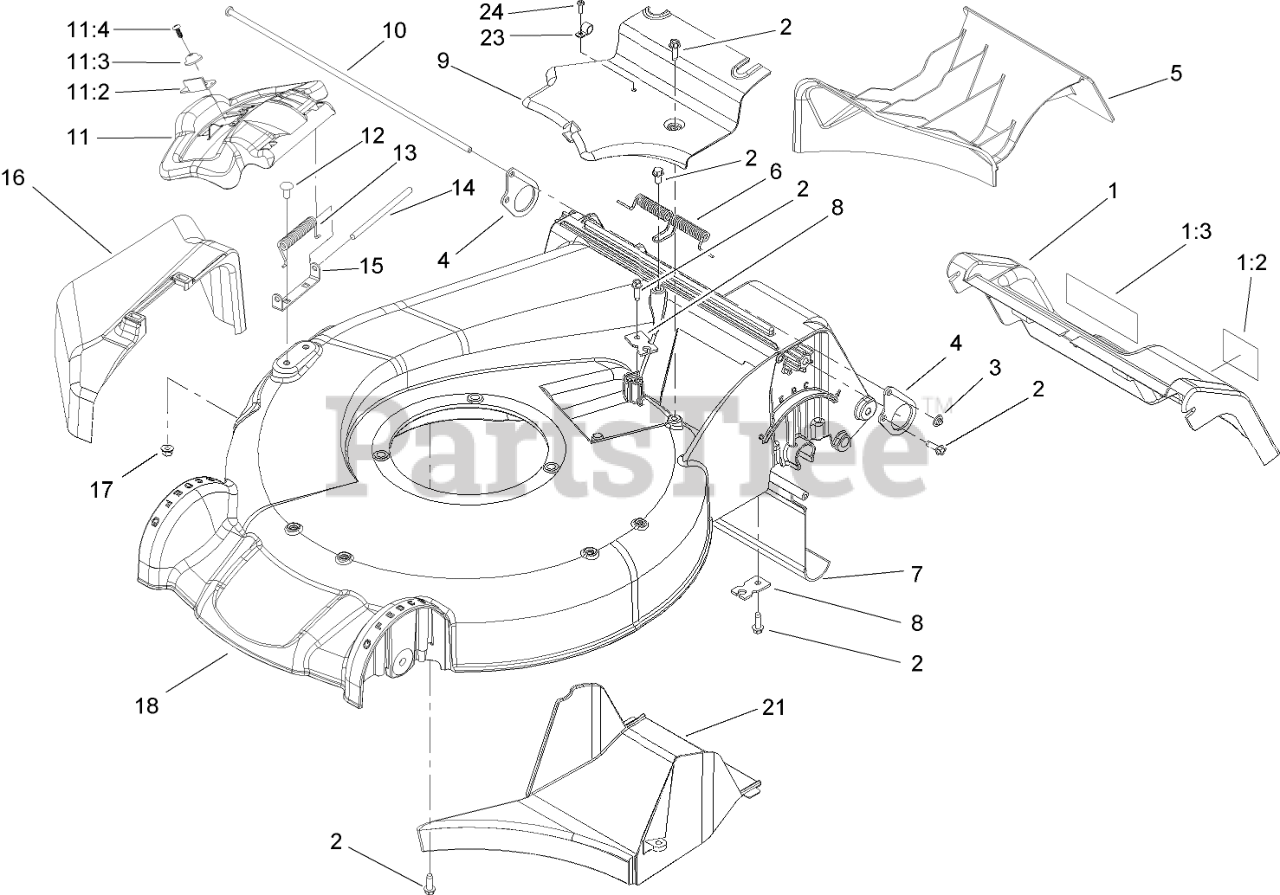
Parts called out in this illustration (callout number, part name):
1	REAR DOOR ASM
1:2	DECAL-WARNING
1:3	DECAL-WARNING
2	SCREW-HWHTF
3	NUT-SPEED
4	PLATE-SUPPORT, DOOR
5	MULCH PLUG ASM
6	Spring-Door, Rear
7	SHIELD-TRAILING
8	BRACKET-CABLE, TRACTION
9	COVER-BELT
10	ROD-SUPPORT, DOOR
11	DISCHARGE DOOR ASM
11:2	LATCH-DOOR
11:3	CAP-DOOR
11:4	SCREW-PLASTITE
12	SCREW-CARR
13	SPRING-TORSION
14	ROD-COVER
15	BRACKET-COVER
16	CHUTE-DISCHARGE, SIDE
17	NUT-HHF
18	HOUSING ASM
21	TUNNEL-DISCHARGE
23	CLAMP
